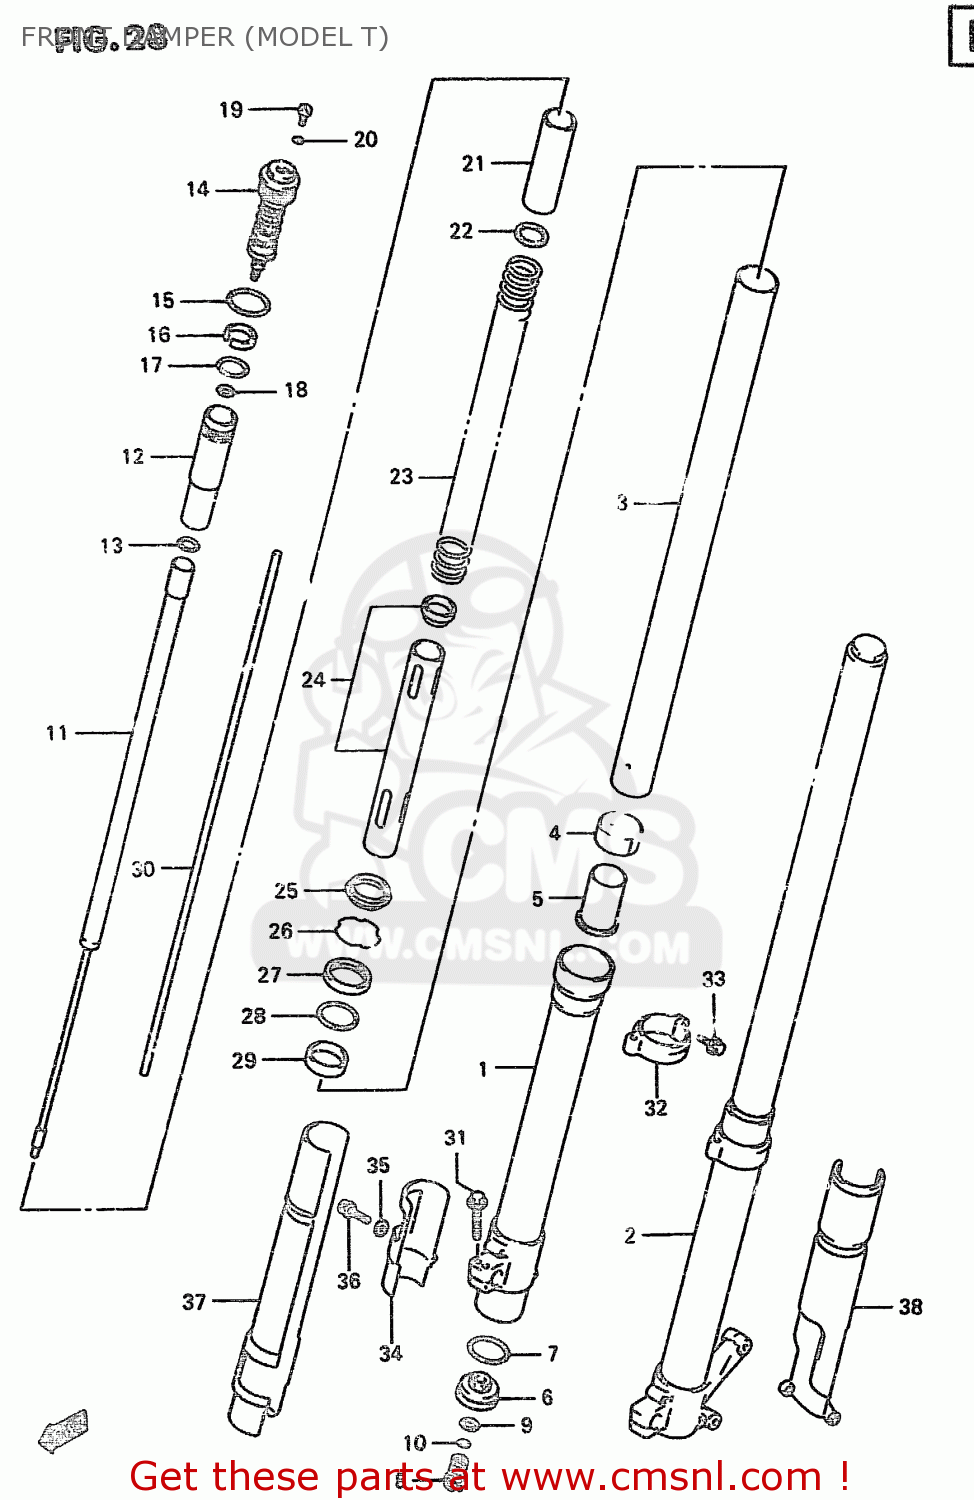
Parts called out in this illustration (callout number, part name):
1	TUBE,OUTER,R
2	TUBE,OUTER,LEFT
3	TUBE,INNER
4	BUSH,SLIDE
5	PIECE,OIL LOCK
6	PLATE,END
7	O RING
8	BOLT,CTR
9	GASKET (NAS)
10	O RING,CTR BOLT
11	DAMPER
12	TANK,SUB
13	O RING,CTR BOLT UPR
14	BOLT,FORK
15	O RING
16	BUSH,FORK BOLT SLIDE
17	O-RING,FORK BOLT,CENTER
18	O-RING,FORK BOLT,LOWER
19	BOLT,PLUG
20	O RING,PLUG
21	COLLAR,SPRING
22	JOINT,SPRING
23	SPRING,FR(K=0.42)
24	COLLAR,SPRING
25	SEAL,DUST
26	RING,STOPPER
27	SEAL,OIL
28	SPACER,SEAL
29	BUSH,GUIDE
30	ROD,PUSH
31	BOLT,HANDLE HOLDER(8X35)
32	GUIDE,FR PROTECTOR,R
33	BOLT,PROTECTOR GUIDE,6
34	PROTECTOR,OUTER TUBE,R
35	WASHER
36	BOLT
37	PROTECTOR,OUTER TUBE,R
38	PROTECTOR,OUTER TUBE,L
